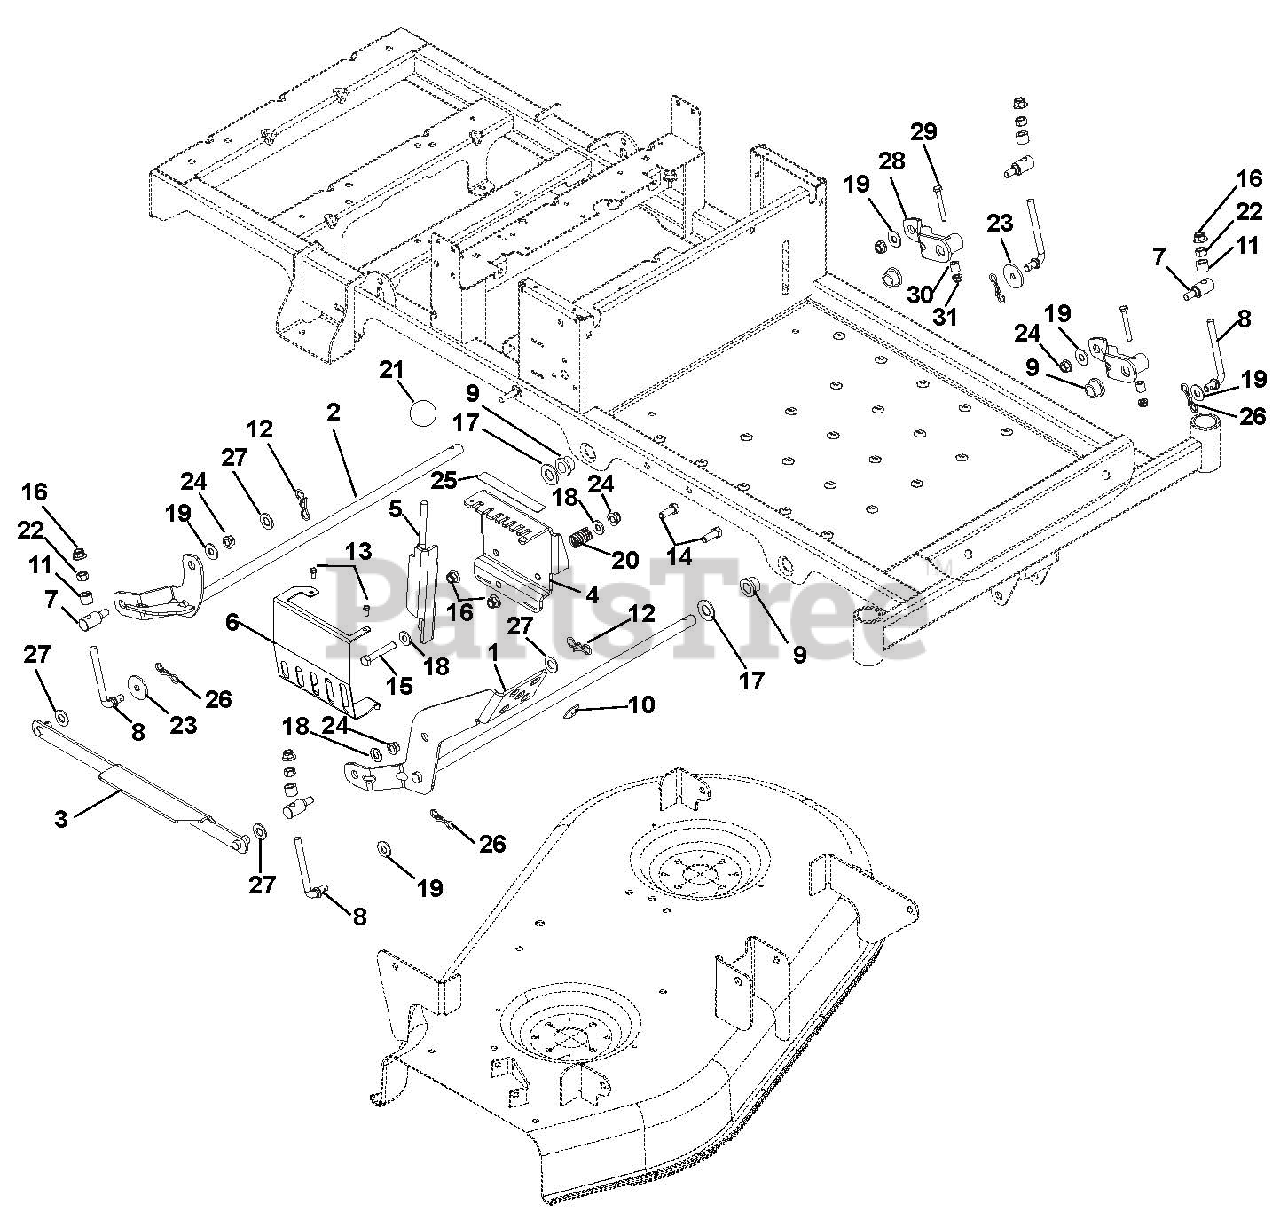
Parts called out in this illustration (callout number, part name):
1	Weldment, Footpedal
2	Weldment, Rear Deck Lift
3	Weldment, Lift/HOC Link
4	Plate, Height Adjustment
5	Weldment, Height of Cut
6	Guard, Deck HOC
7	Trunion, Deck Adjuster
8	Wireform, Deck Adjustment
9	Bushing, Flange .629 x .879 x .469 x 1.25
11	Bushing, Sleeve .391 x .688 x .52
12	Pin, Bow Tie Locking Cotter .091 x 1.875
13	Screw, Tapping, Hex Washer Head Rolling 10-24 x .50
14	Bolt, Hex .38-16 x 1.00
15	Bolt, Hex .38-16 x 2.25
16	Nut, Locking Nylon Flange .38-16
17	Washer, Flat Steel .656 x 1.31 x .095
18	Washer, Flat Steel .38 x .875 x .083
19	Washer, Flat Steel .438 x 1.00 x .083
20	Spring, Compression .125 x .781 x 1.25
21	Knob, Ball – Black 1.47" .375-16
22	Nut, Hex .38-16
23	Washer, Flat Steel .380 x 1.50 x .125
24	Nut, Locking Top Flange .38-16
25	Decal, Height of Cut
26	Pin, Bowtie Locking
27	Washer, Flat Nylon .518 x 1.00 x .08
28	Weldment, Deck Lift Arm
29	Bolt, Hex .25-20 x 2.00
30	Bushing, Sleeve .265 x .500 x .500
31	Nut, Locking Nylon Flange .25-20
